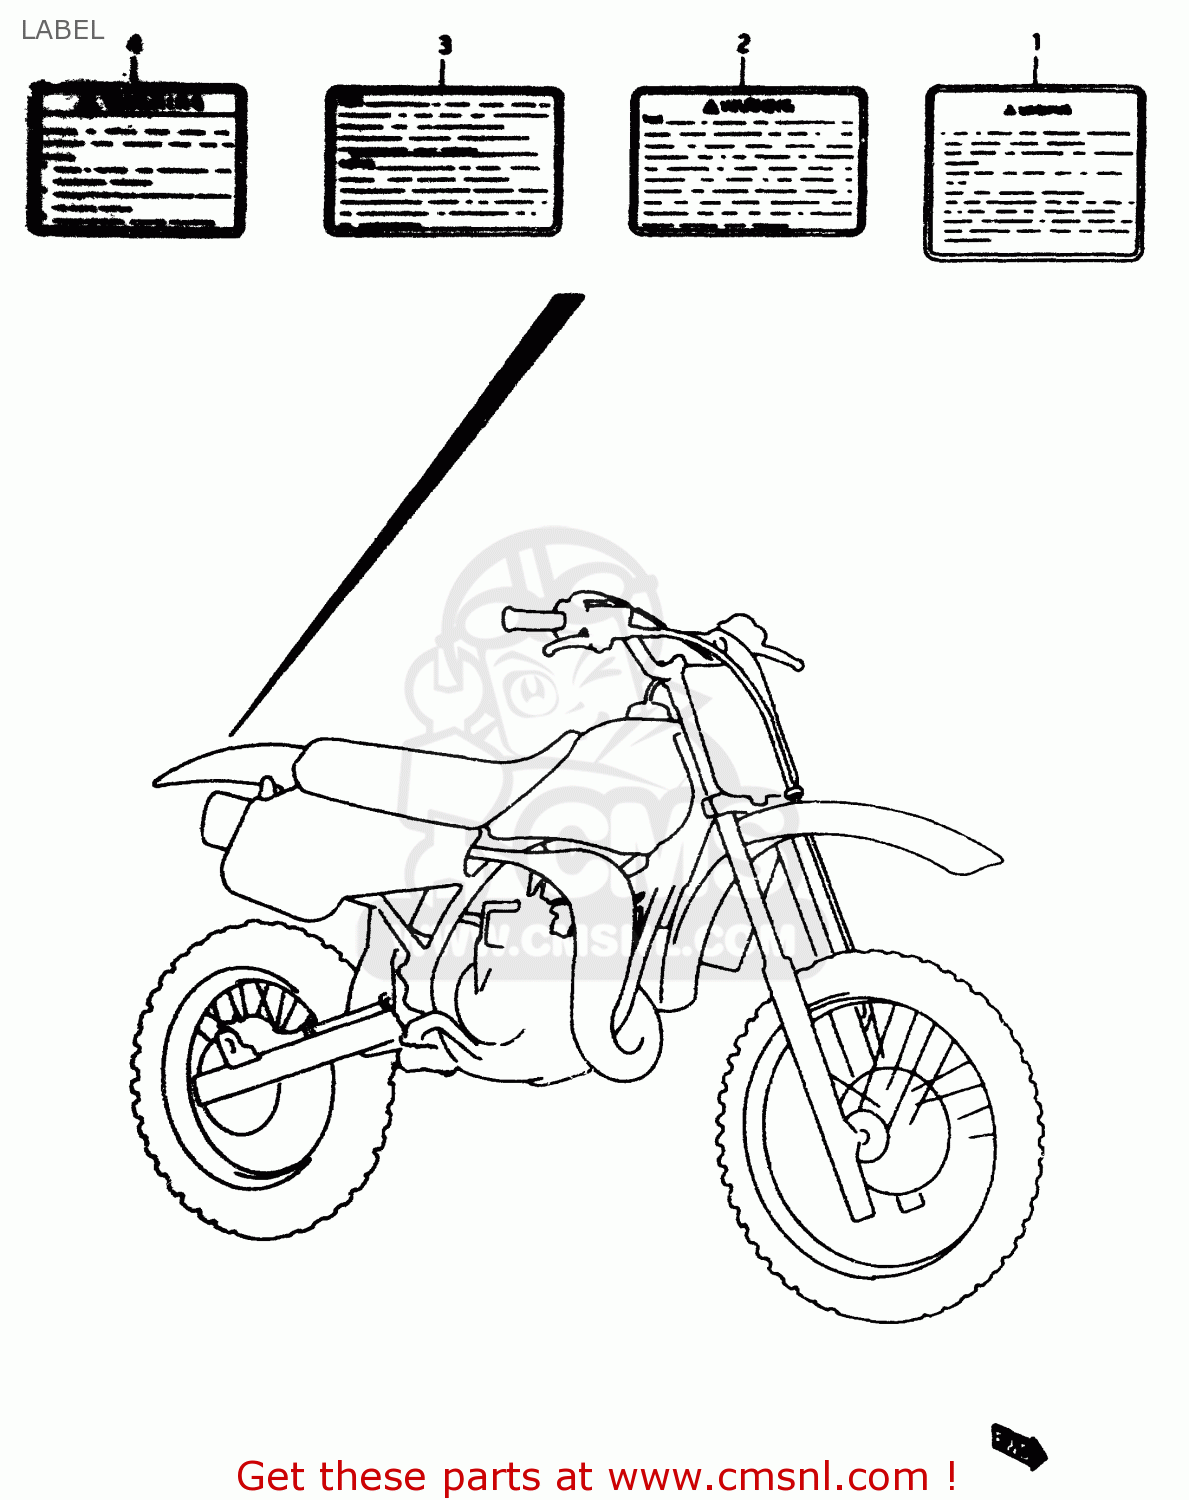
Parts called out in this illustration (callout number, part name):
1	LABEL,WARNING
2	LABEL,WARNING
3	LABEL,WARNING
4	LABEL,WARNING SAFETY
5	LABEL (MANUAL NOTICE)
6	MANUAL,OWNER'S
